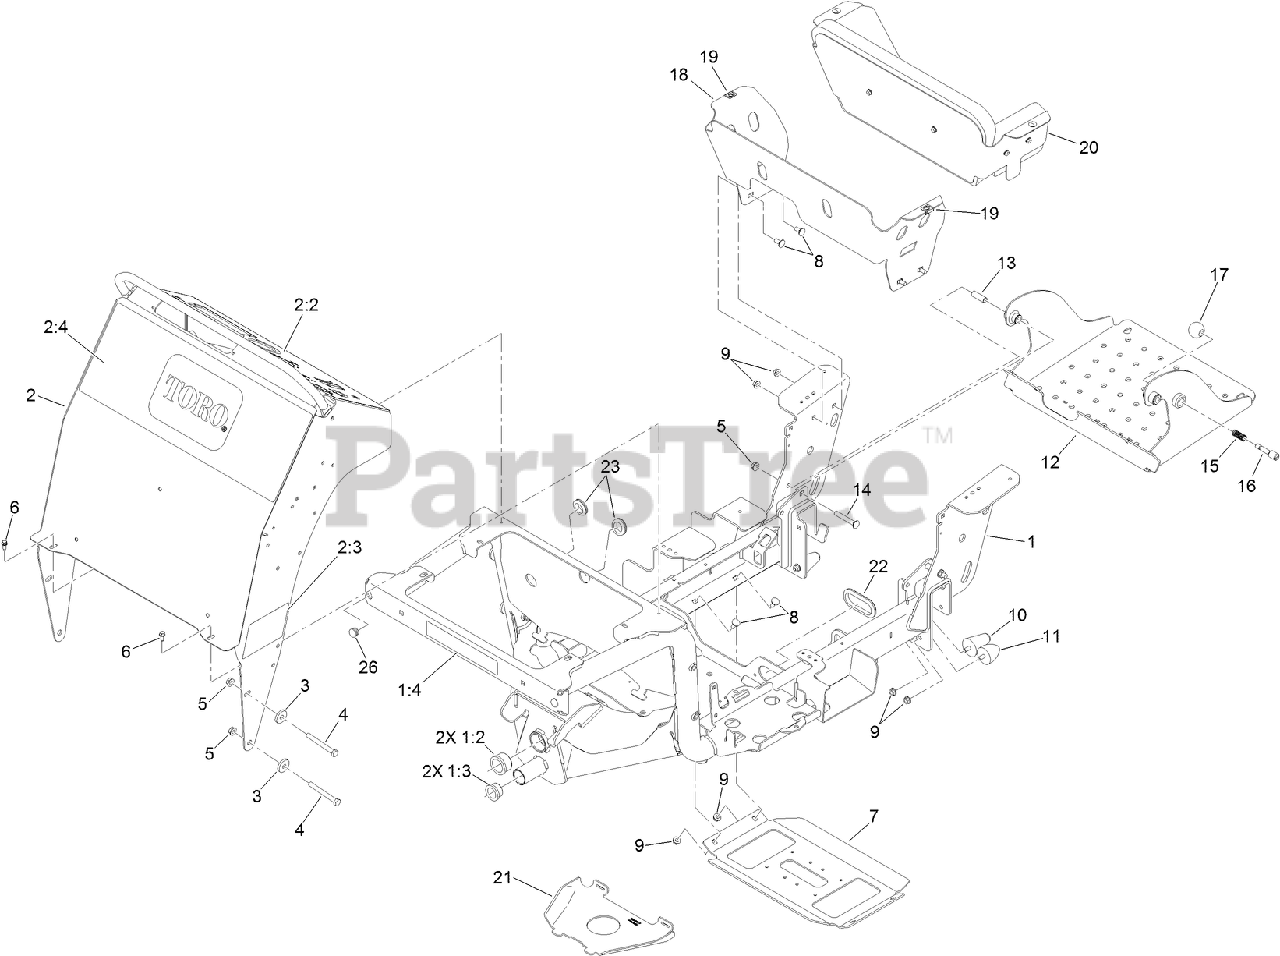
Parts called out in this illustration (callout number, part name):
1	FRAME ASM
1:2	BEARING-FLANGED
1:3	BEARING-FLANGED
1:4	DECAL-DOWN, TIE
2	CONTROL TOWER ASM
2:2	DECAL-CONTROLS
2:3	DECAL-SERVICE AID
2:4	DECAL-TORO
3	WASHER
4	SCREW-HH
5	NUT-HF
6	SCREW-HWH
7	GUARD-LOWER
8	SCREW-CARR
9	NUT-HF
10	BUMPER-RUBBER
11	BUMPER-RUBBER
12	OPERATOR PLATFORM ASM
13	BUSHING-PIVOT, PLATFORM
14	SCREW-CARR
15	SPRING
16	PIN-LATCH
17	KNOB-BALL
18	MOUNT-PAD, KNEE
19	RECEPTACLE-CLIP, MINI
20	KNEE PAD ASM
21	SHIELD-DUST
22	GROMMET
23	GROMMET
26	PLUG-TUBE
